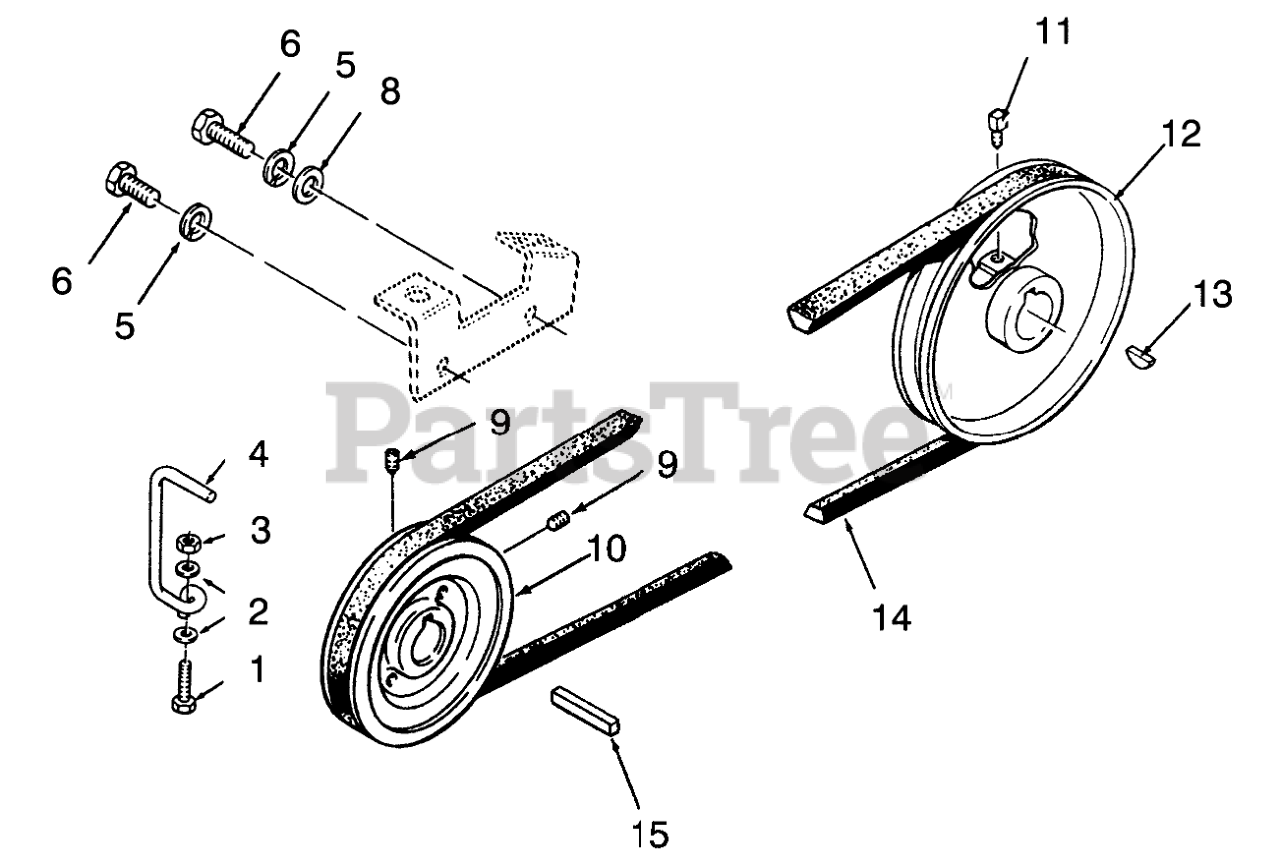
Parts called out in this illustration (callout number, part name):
1	SCREW-HH
2	WASHER-FLAT
3	NUT-LOCK, NI
4	GUIDE-BELT BOTTOM
5	WASHER-LOCK
6	SCREW-HH
8	WASHER-FLAT
9	SCREW-SET, HSH
10	PULLEY
11	SCREW-SQH
12	PULLEY-TRANSMISSION
13	KEY-HI PRO
14	Belt-Drive
